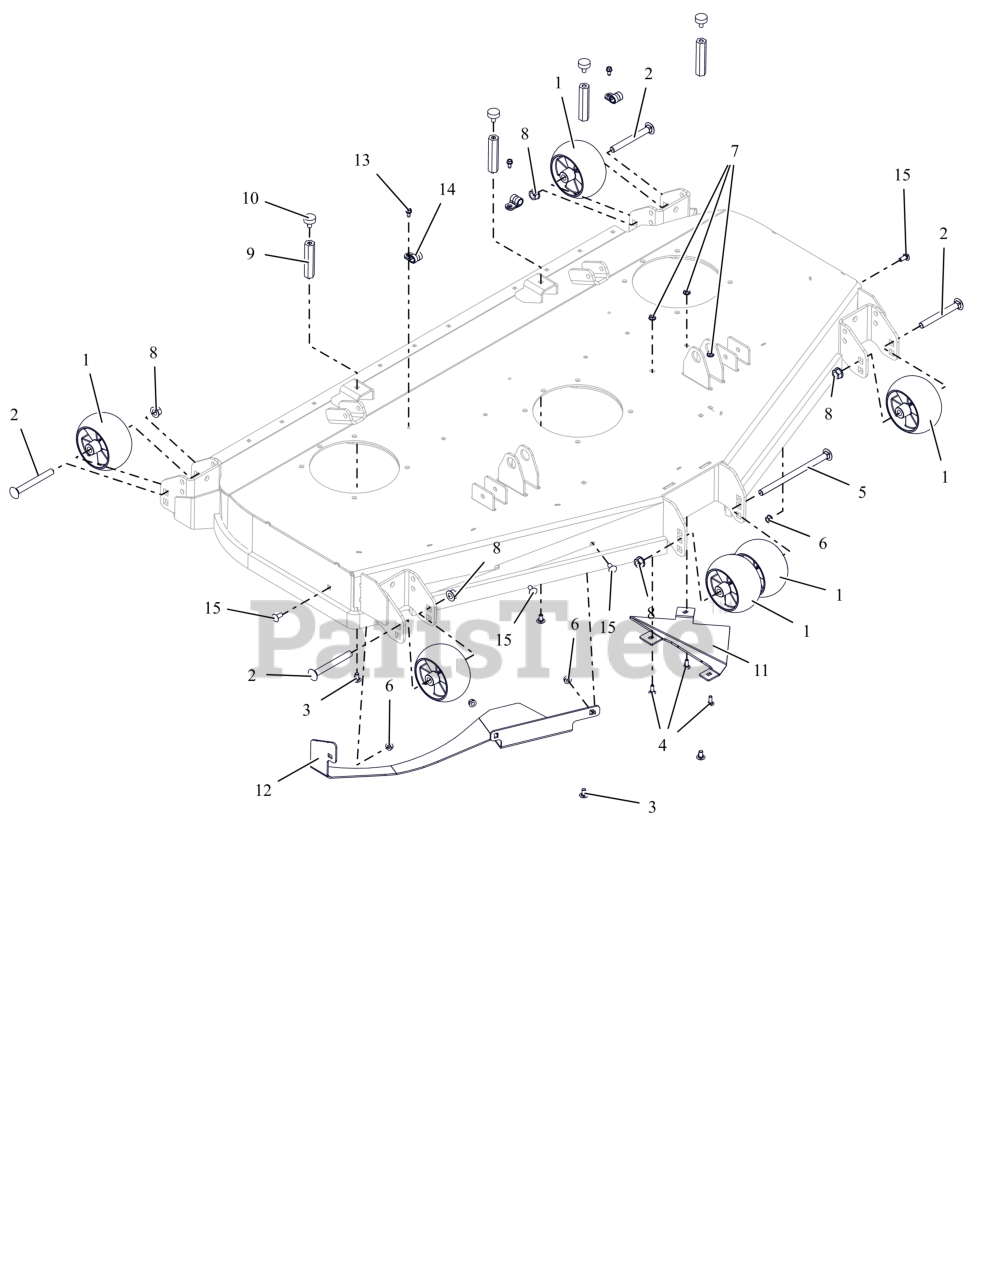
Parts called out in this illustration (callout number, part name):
1	WHEEL, ANTI SCALP - 5X3 CTR W/RIBS
2	BLT-RHNS .50-13X4.50 G5 ZCC NS
3	BLT,RHSSN.31-18X.625 G5 ZCCP30
4	BLT, RHSN .25-20X.750 G5 ZCC
5	BLT-RHSN .50-13X8.00 G5 ZCC NS
6	NUT,LK-CTR-FLG .31-18 GF ZCC
7	NUT-LK-CTR-FLG .25-20 ZC120
8	NUT-LK-CTR-FLG .500-13 GG ZCC
9	NUT, COUPLING .312-18 X 3.375
10	BUMPER, RUBBER
11	BAFFLE, INSERT TRIANGLULAR (ORANGE)
12	DEFLECTOR, BAFFLE BOLT-IN (ORANGE)
13	SCR-TAP .25-20X.50 HWH ZCC
14	CLAMP, CUSHIONED STEEL
15	BLT, RHSSN.31-18X.750 G5 ZCC
